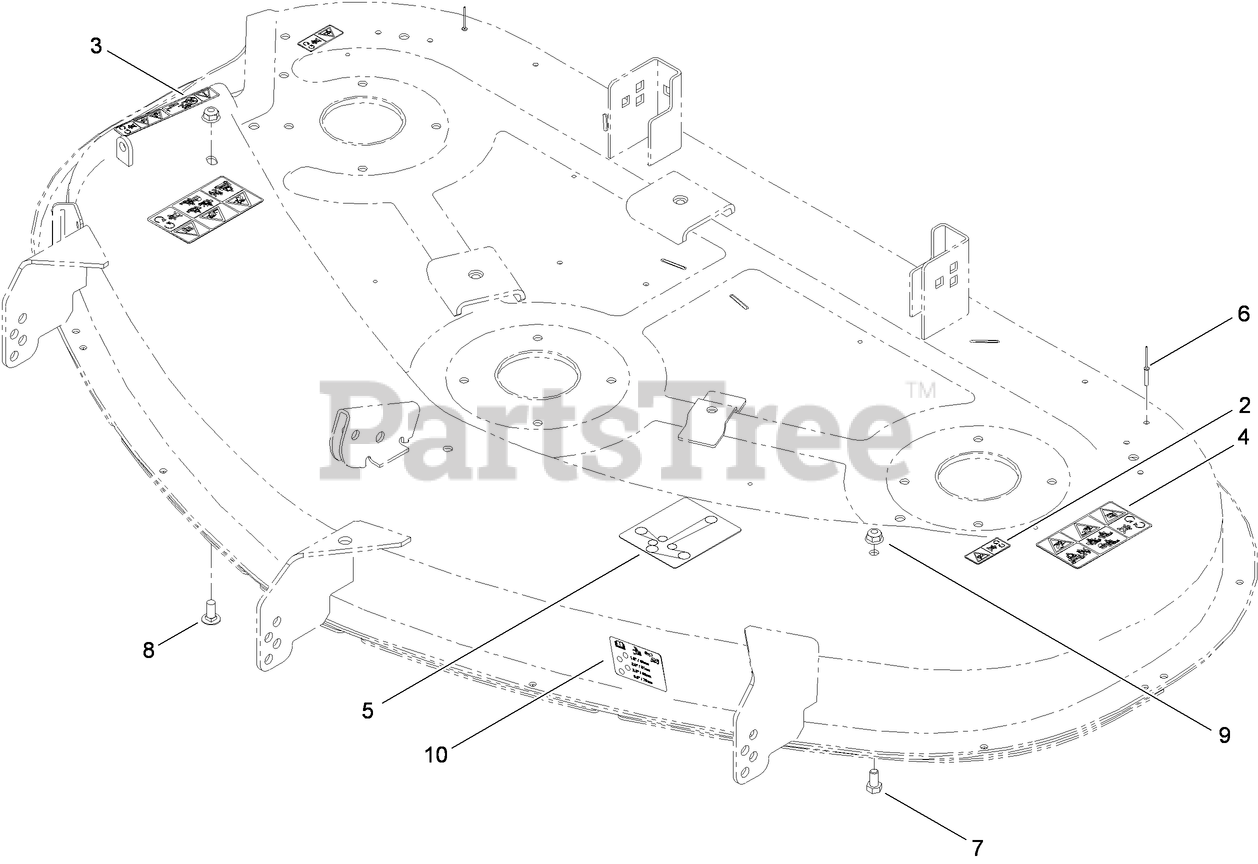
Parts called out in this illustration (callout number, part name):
2	DECAL-DANGER
3	DECAL-DANGER
4	DECAL-DANGER
5	DECAL-ROUTING, BELT
6	RIVET-BLIND
7	SCREW-HH
8	SCREW-CARR
9	NUT-HF, NI
10	DECAL-SCALP, ANTI
